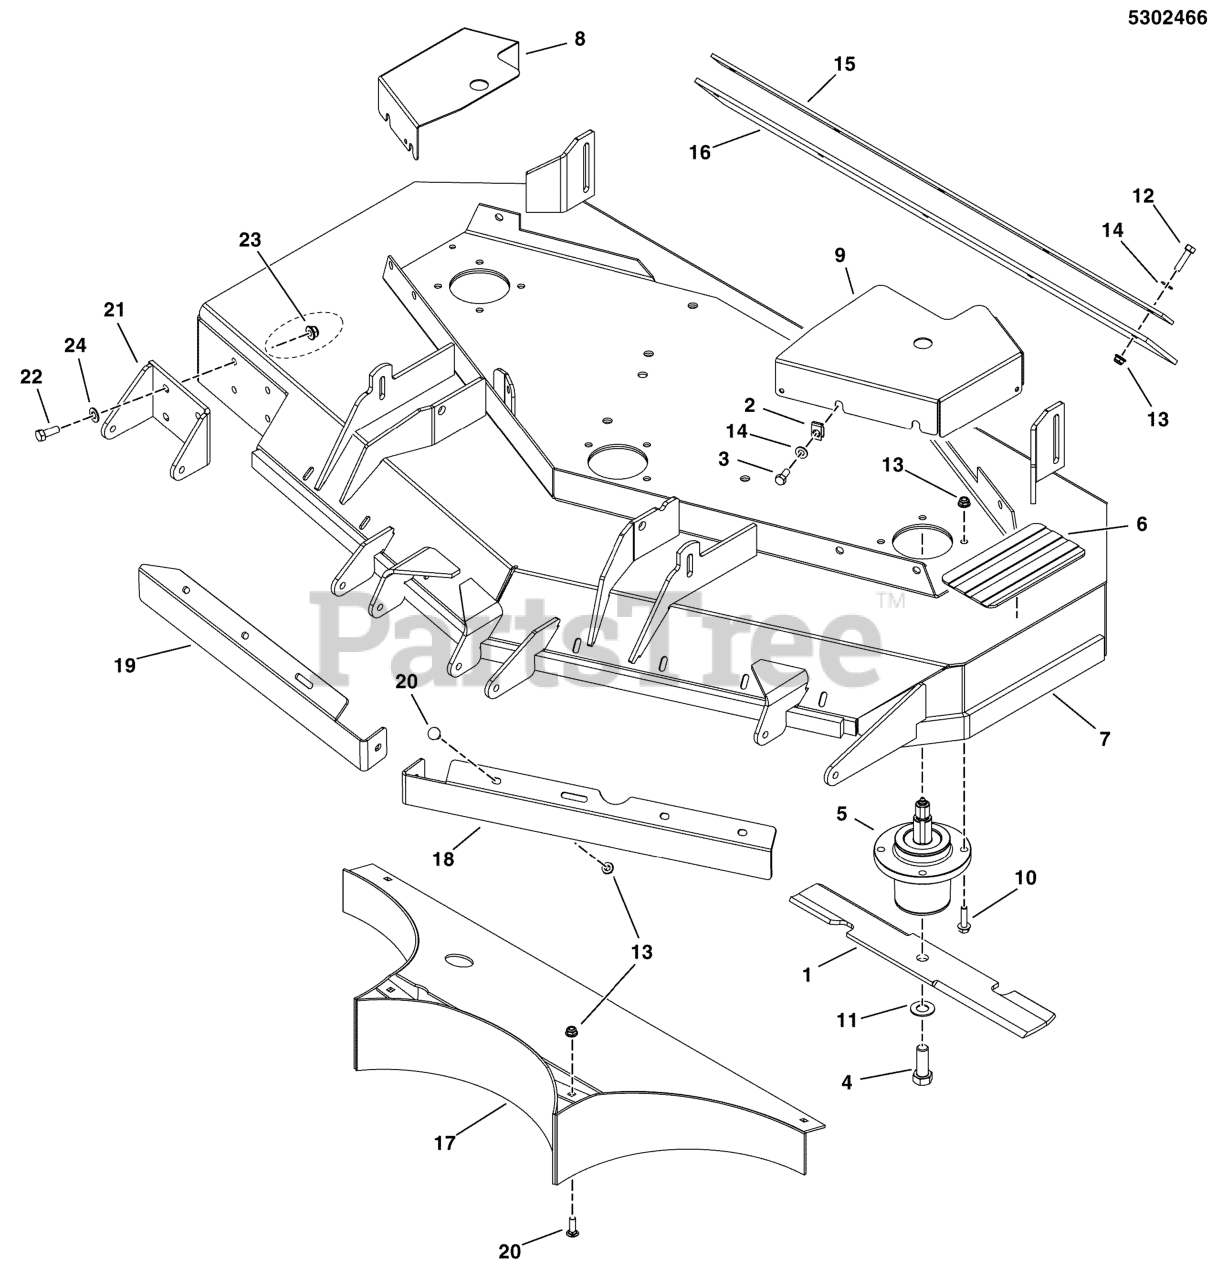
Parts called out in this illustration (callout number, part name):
1	BLADE, 18 X .25 X 2.5, 1 X 3.5 (SET OF THREE)
2	BODY CLIP, 5/16-18-7GA MATERIAL
3	BOLT, 5/16-18 X 3/4 GD5
4	BOLT, 5/8-11 X 1-3/4 GD8
5	ASSM, SPINDLE, LOW PROFILE
6	SAFETY WALK, 4.00 X 7.50
7	DECK SHELL W/DECALS, 52", IS1500 RD
8	GUARD, 52" DECK, IS2000 - RH - RED
9	GUARD, 52 DECK, IS1500Z, LH - RED
10	BOLT, 5/16-18 X 1 1/4 FLANGE
11	WASHER, 5/8 GRADE 8, YZ
12	BOLT, 5/16-18 X 1-1/4 GD5 YZ
13	NUT, 5/16-18 HEX NYLOCK FLANGE
14	WASHER, 5/16" SAE
15	PLATE, FLAP RETAINER, 2000 RD - BLK
16	FLAP, 2000 REAR DISCHARGE
17	WELD, REAR BAFFLE, 52 RD - BLK
18	BAFFLE, FRONT DISCHARGE, LH, S150XCE-RED
19	BAFFLE, FRONT DISCHARGE, RH, S150XCE-RED
20	BOLT, 5/16-18 X 1, CARRIAGE
21	PLATE, BRACKET, ANTI SCALP - RED
22	BOLT, 3/8-16 X 1-1/4" GD5 CZ
23	NUT, 3/8-16 HEX NYLOCK FLANGE
24	WASHER, 3/8 SAE
